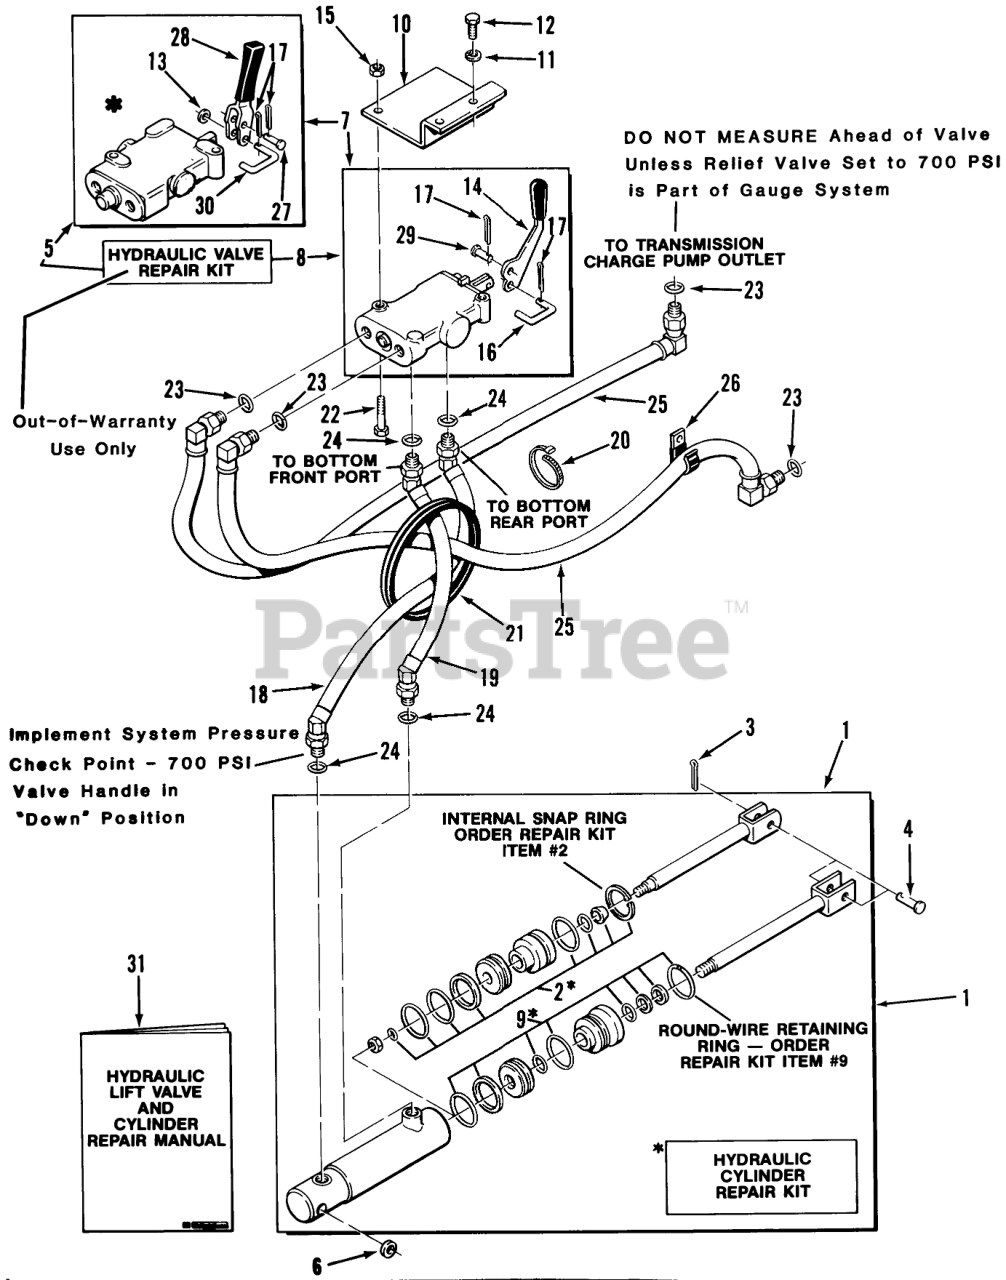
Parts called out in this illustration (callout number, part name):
1	CYLINDER
2	S/A O-RING&GASKET AS
4	CLEVIS PIN
5	S.A. Valve Repair Kit
6	Spacer
7	Hydraulic Valve
8	S/A 110068 VALVE
9	S/A 108872 HYD CYL
10	ASSY VALVE SUPPOR B
11	Lockwasher
12	Bolt
13	WASHER
14	VALVE HANDLE
15	Nut
16	C-HOOK
17	Cotter Pin
18	Hose-Valve To Cylinder
19	Hose-Valve To Cylinder
20	PLASTIC TIE
21	GROMMET
22	Screw-Hex. Hd.
23	0-Ring
24	O RING
25	ASSY HOSE HYDRAULIC
26	CLIP
27	CLEVIS PIN
28	Valve Handle
29	Pin
30	Link Wire
31	Repair Manual
